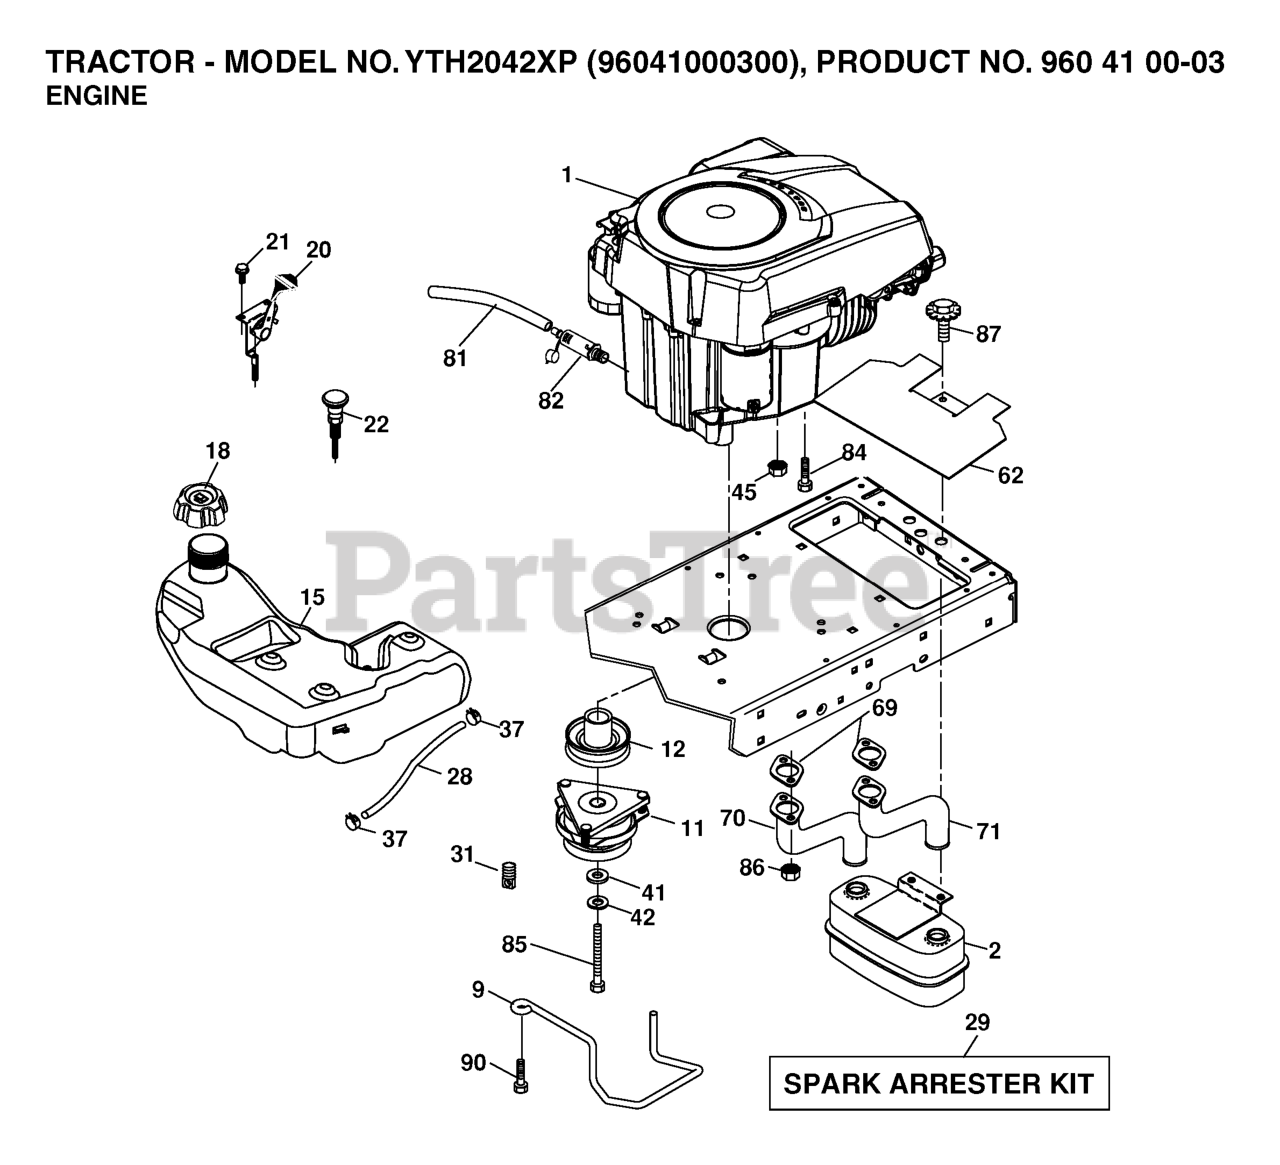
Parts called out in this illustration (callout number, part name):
2	MUFFLER.TWIN.CYL.LOW.TONE
9	KEEPER.BELT.ENGINE.3.25 (3 2)
11	RB.CLUTCH.OGURA.4.4.PD
12	PULLEY.ASM.ENG.OGURA.3
15	TANK.FUEL.4GAL
18	CAP.FUEL.TANK.3"GREY
20	THROTTLE CONTROL
21	SCREW
22	CONTROL.CHOKE.ERGO.PUSH-IN.BLA
28	REPL BY 532 00 85-43
29	KIT.SPARK ARRESTOR 794945 B&S
37	HOSE CLAMP
42	LOCKWASHER
45	NUT
62	RP SHIELD HEAT MUFFLER
70	RP.PIPE-EXHAUST LH
71	RP.PIPE-EXHAUST RH
81	TUBE, DRAIN OIL ASM.
82	PLUG DRAIN OIL EASY
84	SCREW.3/8-16
85	BOLT HEX 7/16-20X4-1/4"
86	NUT.HEX.FLANGE.TOPLOCK
87	BOLT.5/16-18UNCX1.W/SEMS.BLK
90	SCREW 3/8-16X1
